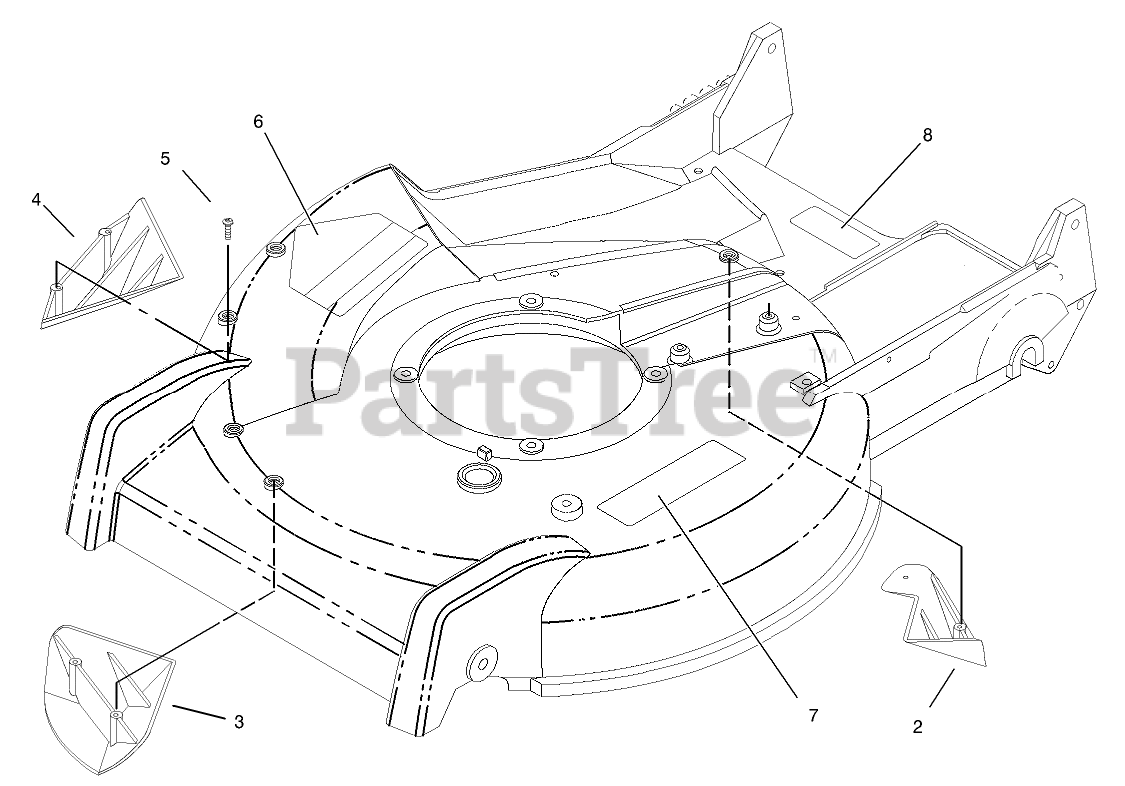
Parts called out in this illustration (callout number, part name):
2	KICKER-REAR
3	KICKER-FRONT
4	KICKER-RH
5	SCREW-PPH
6	DECAL-DANGER
7	DECAL-WARNING
8	DECAL-WARNING
